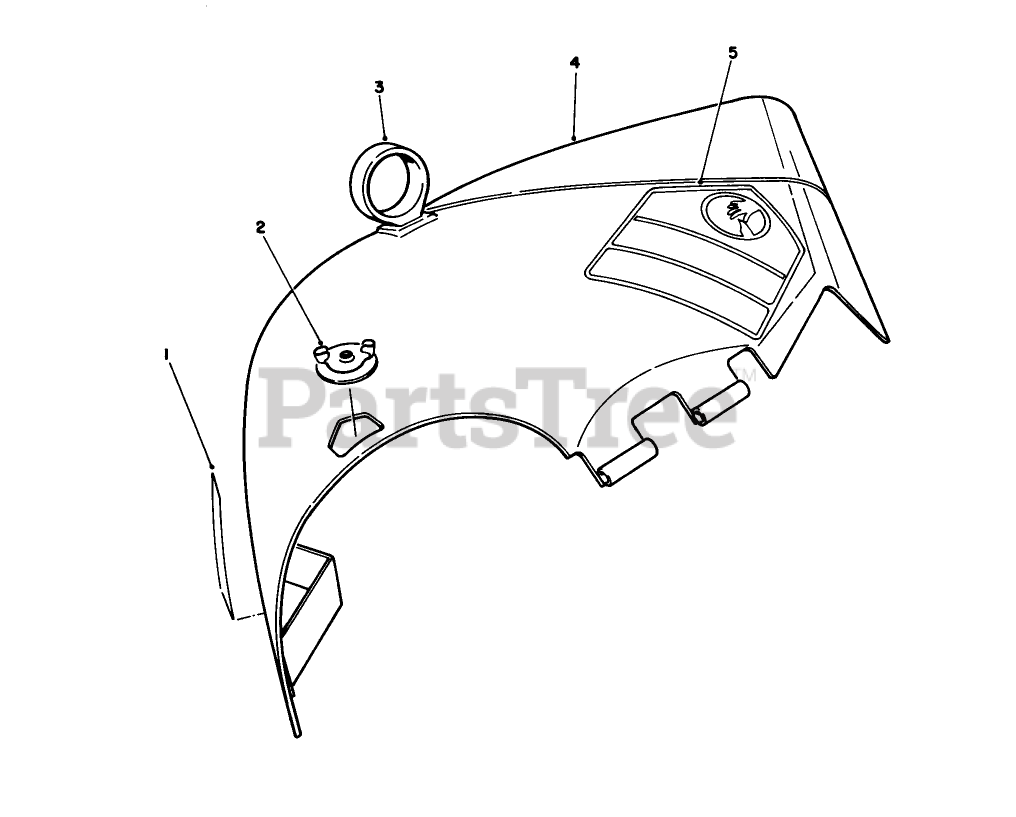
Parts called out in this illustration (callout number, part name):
1	DECAL-DANGER DEFLECTOR
2	Wingnut W.A.
3	LIFT LOOP
4	Deflector W.A.
5	DECAL-DANGER
